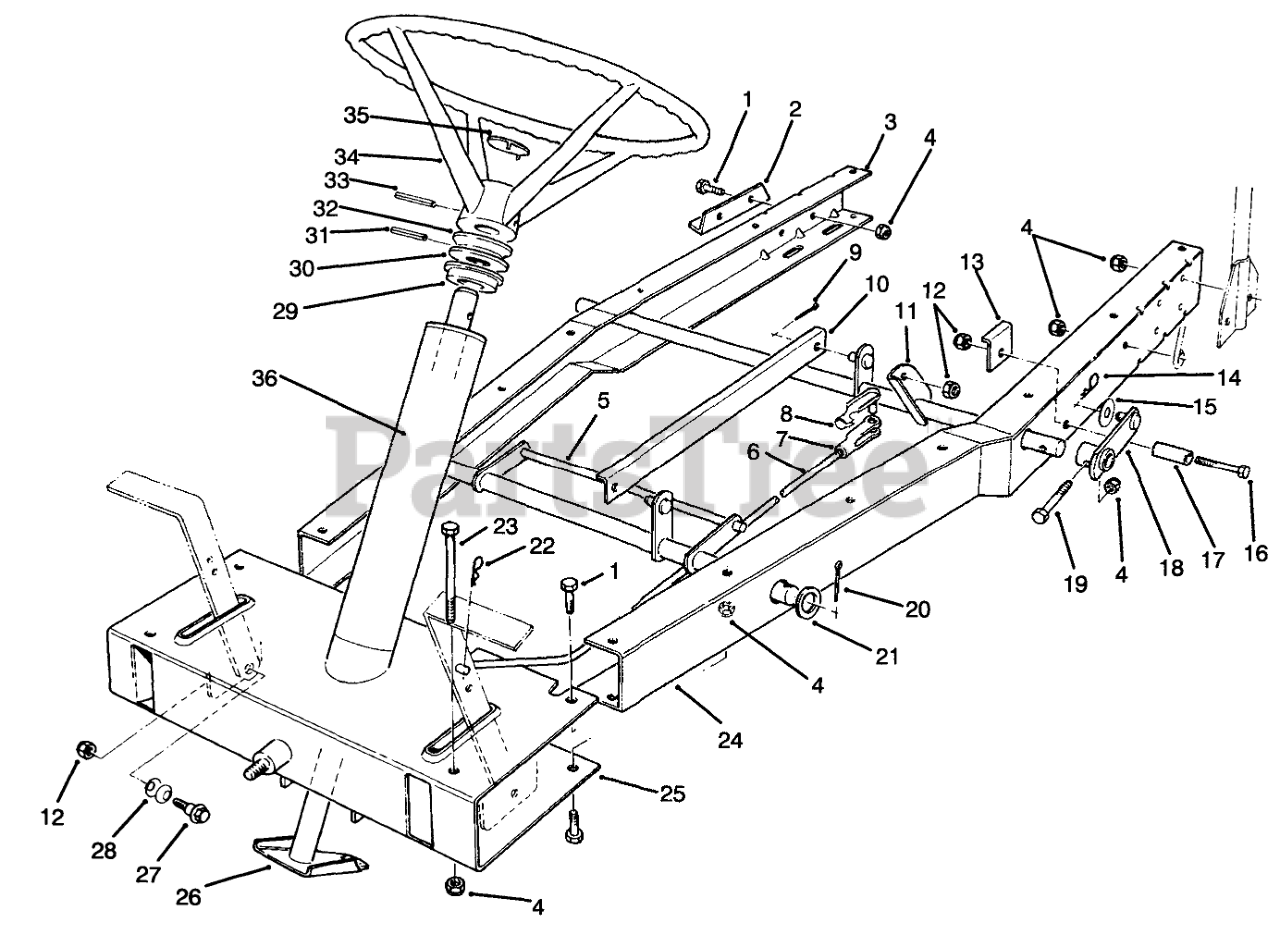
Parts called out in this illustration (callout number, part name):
1	SCREW-HH
2	MOUNT-AXLE BRG
3	FRAME-CHANNEL RH RED
4	NUT-LOCK, NI
5	FRT DECK LIFT WA BLACK
6	ROD-CLUTCH
7	CLEVIS-ADJ
8	Assembly-Pin, Clevis
9	PIN-COTTER
10	HOC BRKT LINK BLACK
11	REAR SUP TUBE WA RED
12	NUT-LOCK, NI
13	DECK STOP BRACE (BLACK)
14	PIN-HAIR
15	WASHER
16	SCREW-HH
17	SPACER-STOP,DECK
18	HOC LEVER WA RED
19	AXLE MTG BOLT
20	PIN-COTTER
21	WASHER-FLAT
22	PIN-COTTER
23	SCREW-HH
24	FRAME-CHANNEL LH
25	FRONT FRAME WA RED
26	STEERING SHAFT WA BLK
27	BOLT-SHOULDER
28	WASHER-BELLEVILLE
29	BUSHING-STEERING
30	WASHER-STEERING
31	PIN-ROLL
32	SPACER-STEERING
33	PIN-ROLL
34	STEERING WHEEL ASM
35	STEERING WHEEL INSERT
36	DECAL - STEERING COLUMN
